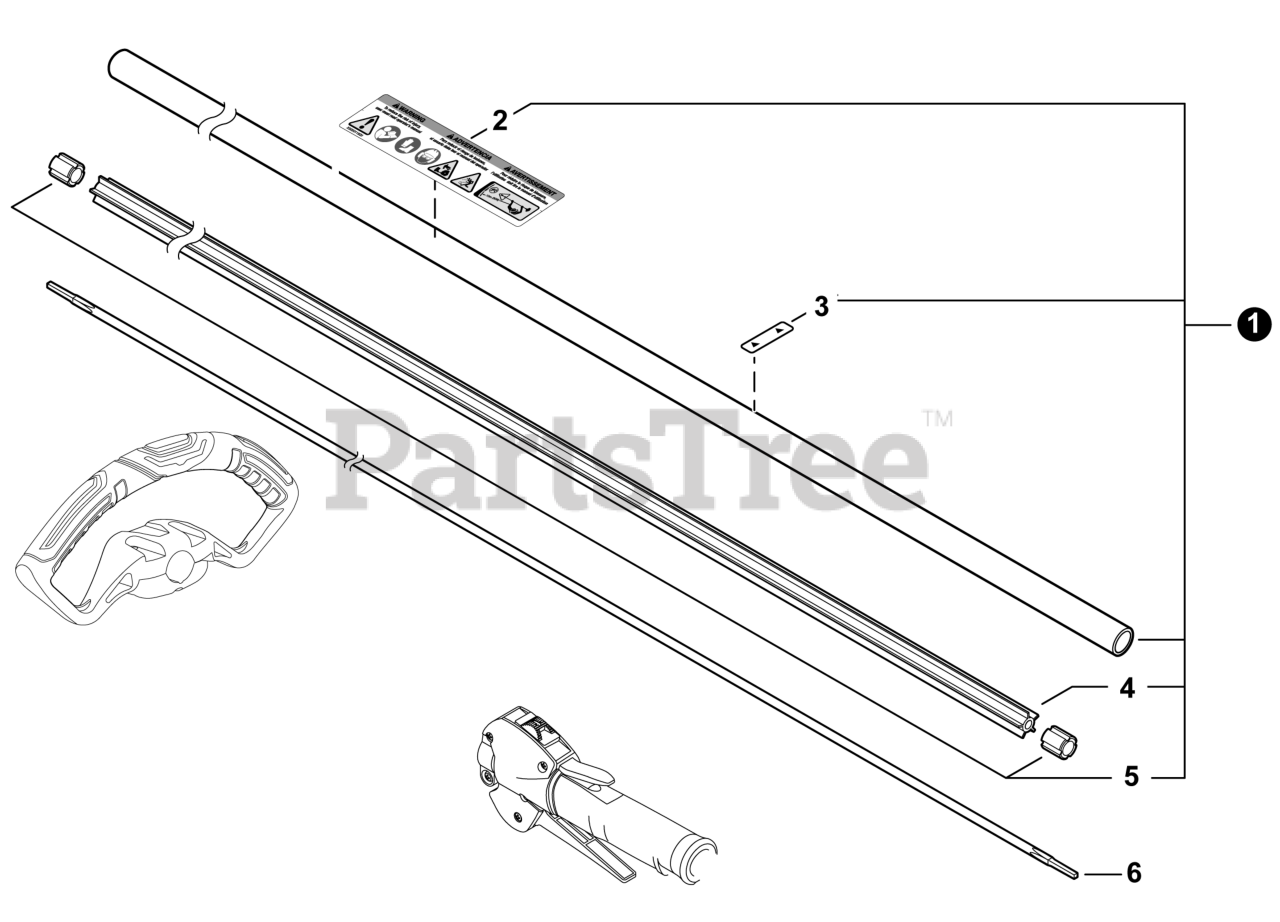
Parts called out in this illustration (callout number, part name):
1	MAIN PIPE ASSY
2	LABEL - CAUTION ISO
3	LABEL - ALIGNMENT
4	LINER, FLEXIBLE
5	STOPPER
6	DRIVESHAFT - FLEXIBLE
